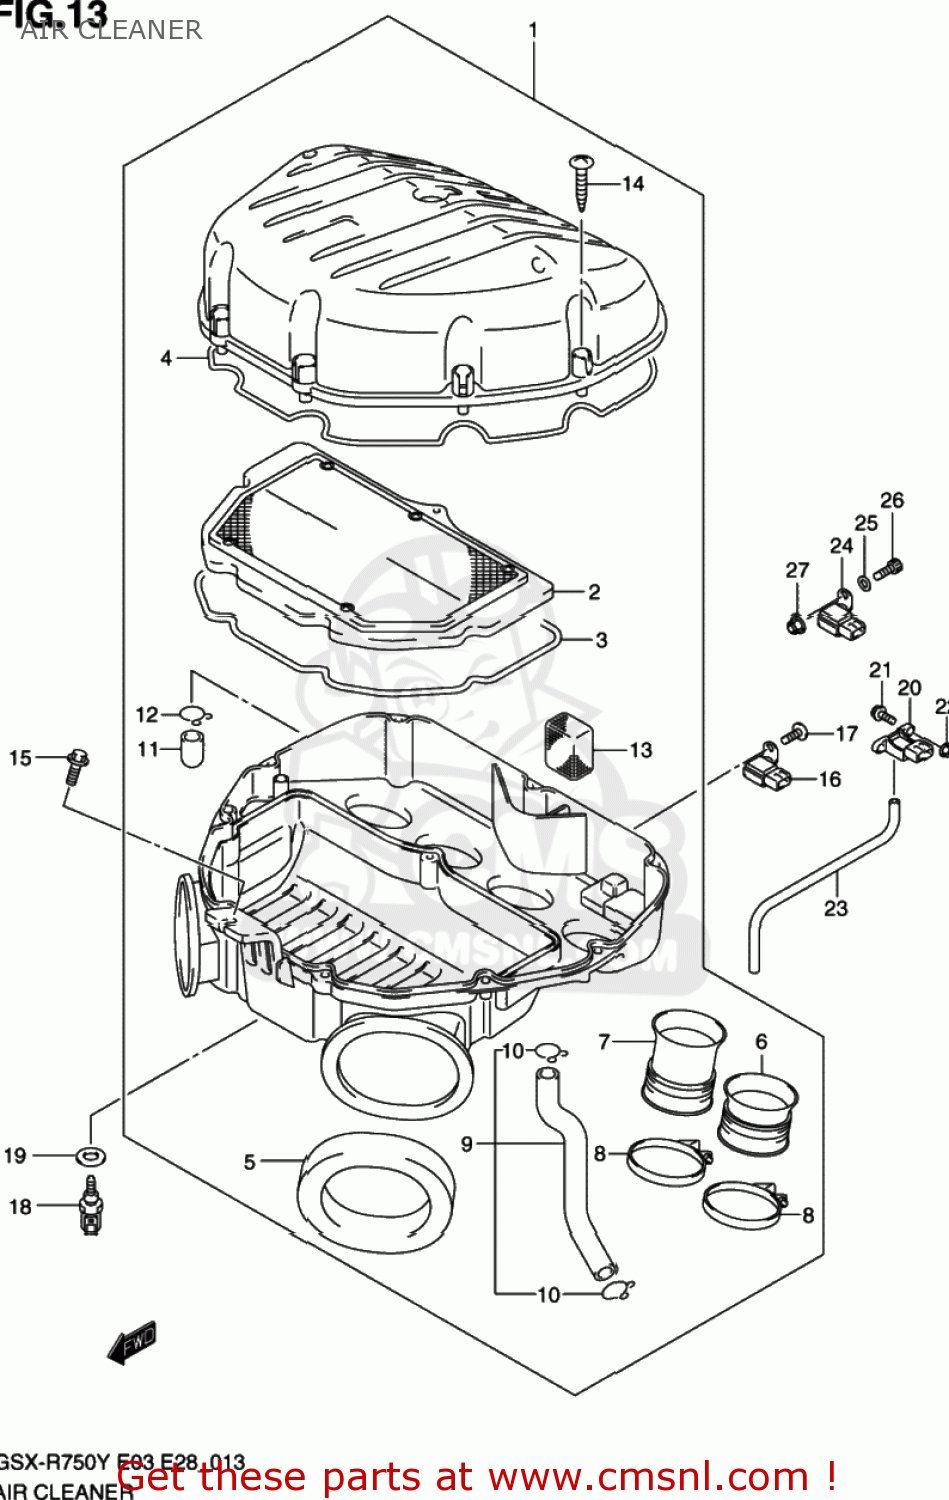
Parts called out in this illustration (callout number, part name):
1	CLEANER ASSY,AIR
2	FILTER ASSY,AIR CLEANER
3	GASKET,CASE (NAS)
4	GASKET,CAP (NAS)
5	CUSHION,DUCT
6	TUBE,OUTLET,L/R
7	TUBE,OUTLET ML/MR
8	CLAMP
9	TUBE,BREATHER
10	CLIP
11	PLUG
12	CLIP
13	FILTER,BREATHER
14	SCREW
15	BOLT(6X16)
16	SENSOR,BOOST
17	SCREW 6X10
18	SENSOR,WATER TEMP
19	GASKET(12X17X1) (NAS)
20	SENSOR,MAP
21	BOLT MAGNETO S
22	NUT
23	HOSE,AIR PRESS SENSOR
24	SENSOR,BOOST
25	WASHER(6.5X20X1.2)
26	BOLT,OIL FILLE
27	NUT
